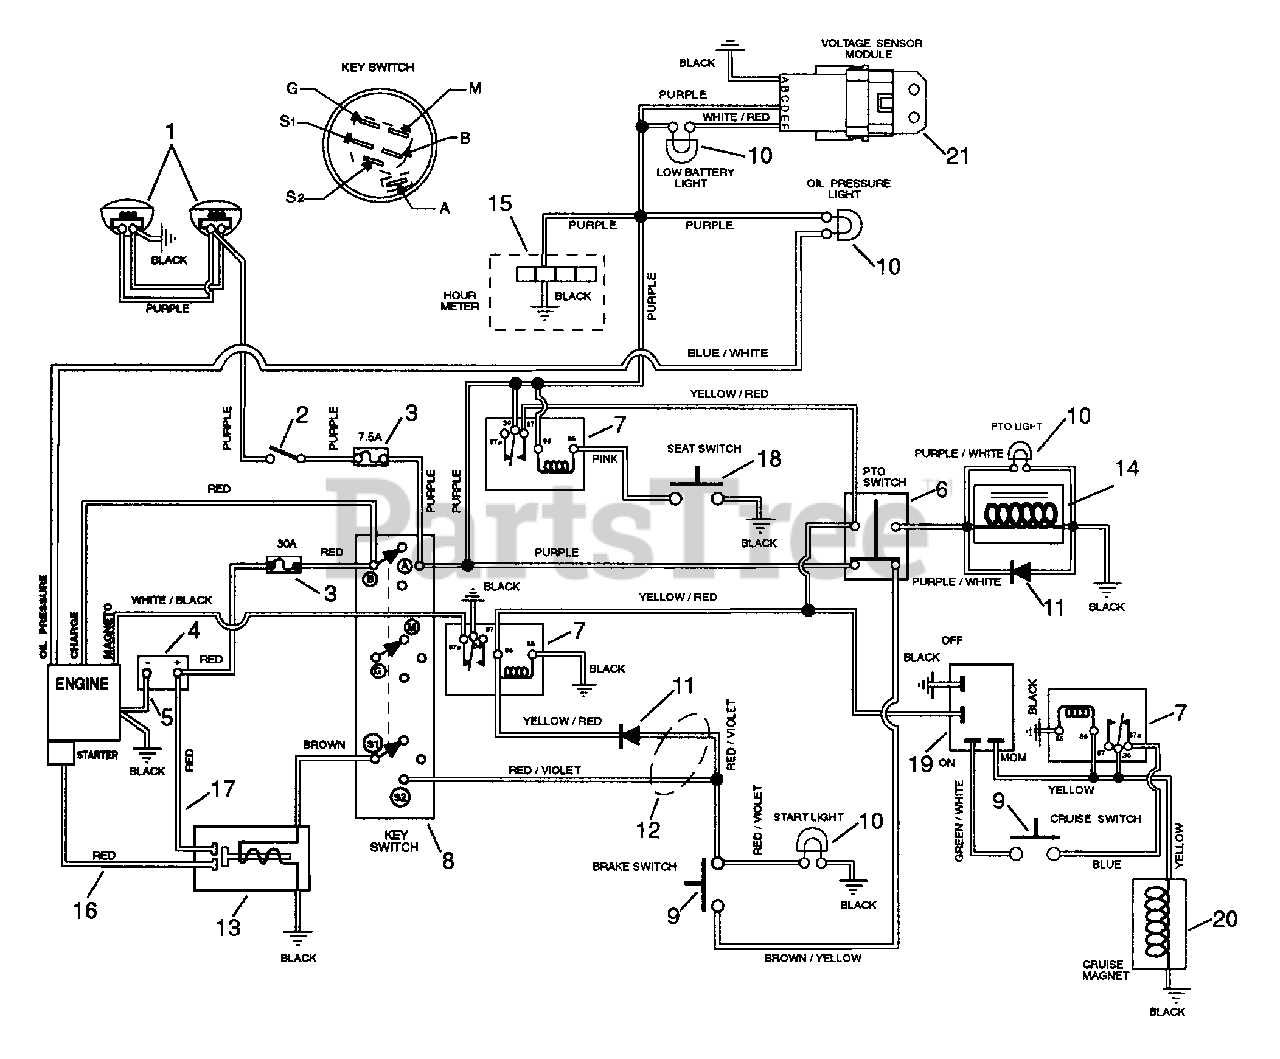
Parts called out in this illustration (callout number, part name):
1	HEADLIGHT- RH
1	HEADLIGHT- LH
2	SWITCH - LIGHT
3	7.5 AMP Fuse
3	30 AMP Fuse
4	BATTERY W/TUBE
5	GROUND CABLE .31X22.00X.31
6	PTO KNOB/ SWITCH ASSY
7	RELAY
8	KEY SWITCH
9	SWITCH- SINGLE POLE N.O.
10	#194 Bulb
11	MOLDED DIODE PLUG 1 AMP
12	WIRE HARNESS - 1540H KOHLER
13	SOLENOID
14	ELECTRIC CLUTCH/BRAKE (3.4AMP)
15	HOURMETER KIT- SIERRA
16	START CABLE 22"
17	STARTER CABLE 6.75"
18	SWITCH- SEAT
19	SWITCH - CRUISE
20	MAGNET
21	MODULE - VOLTAGE SENSOR
